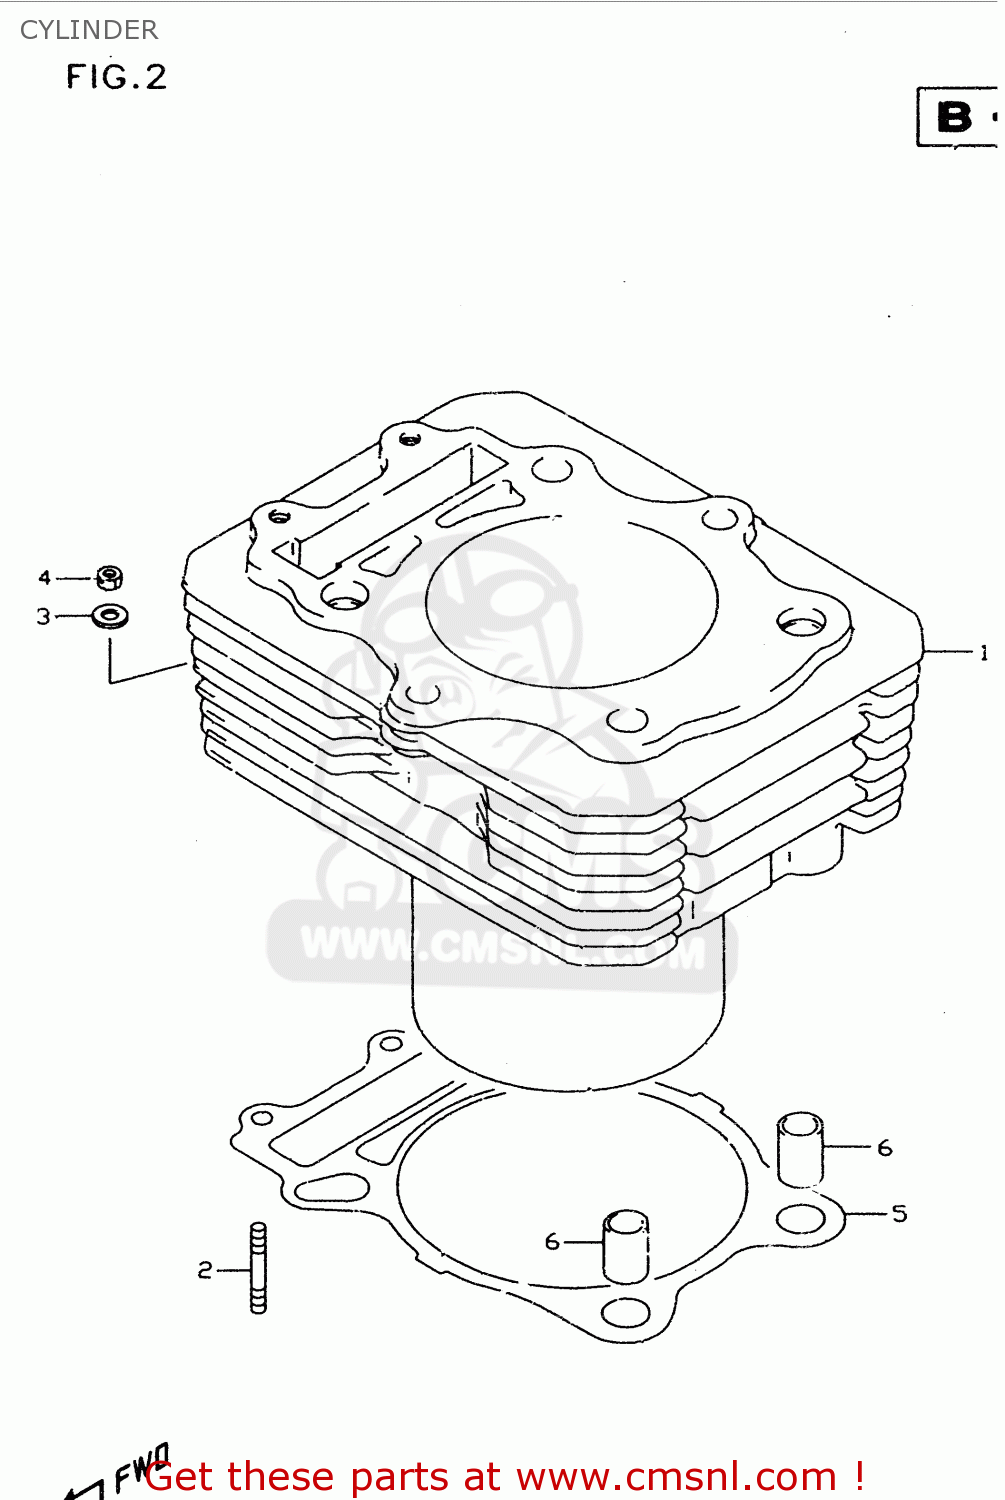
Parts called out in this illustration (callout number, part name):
1	CYLINDER
2	STUD 6X20
3	WASHER
4	NUT
5	GASKET,CYLINDER (NAS)
6	PIN
